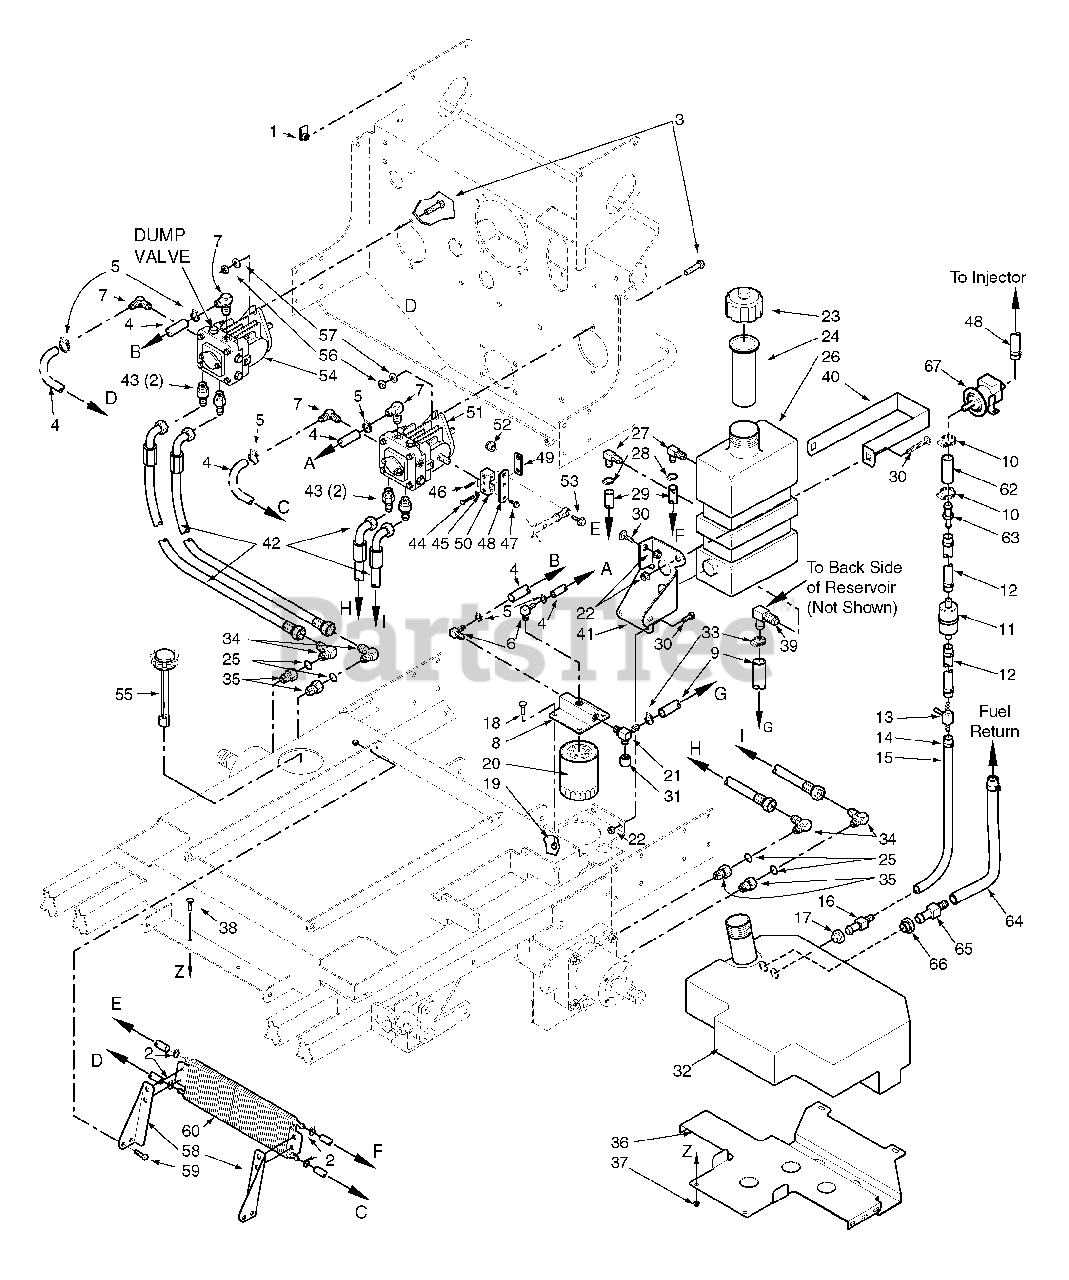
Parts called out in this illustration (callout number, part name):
1	U-Nut 1/4-20
2	Hose Clamp, 0.69 dia.
3	Bolt, Hex Head 1/4-20 x 2.0"
4	Hose, 3/8" ID Pushlock
5	Clamp, Hose 1/2"
6	Elbow, 90 Degree - 1/4 NPT x 3/8 Hose
7	Elbow, 90 Degree - 9/16 O-ring x 3/8 Hose
8	Oil Filter Base
9	Hose Assembly, 1/2" ID (Tank to Filter Base)
10	Clamp, .87 max Dia.
11	Fuel Filter, Kawasaki
12	Fuel Hose, 5/16" ID.
13	Valve, Shutoff Kawasaki
14	Clamp, Fuel Hose
15	Fuel Hose, 5/16" ID.
16	Hose Fitting
17	Bushing
18	Bolt, Hex Head 5/16-18 x 1.0" Zinc
19	Nut, Serrated Flange 5/16-18
20	Oil Filter
21	Tee, 3/4 O-ring x JIC x 1/2" Hose
22	Nut, Hex Elastic Stop 1/4-20
23	Cap, Hydraulic Tank
24	Insert, Filler Neck
25	O-Ring
26	Oil Reservoir Assembly
27	Elbow, 90 Degree .38 Hose
28	Hose Clamp, 0.69 dia.
29	Hose, 3/8" ID, Pushlock
30	Screw, Phillips Head, 1/4-20
32	Fuel Tank Assembly
33	Clamp, Hose
34	Elbow, 90 Degree, 7/8-14 THD
35	Bushing, 7/8-14 JIC x 3/4-16 O-Ring
36	Support Bracket, Fuel Tank
37	Nut, 5/16-18 Serrated Flange
38	Bolt, Carraige 1/4-20 x 3/4"
39	Elbow, 90 Degree
40	Strap, Hydraulic Tank
41	Support Bracket, Hydraulic Tank
42	Hose Assembly, Pump
43	Union, 3/4-16 JIC x 3/4-16 O-ring
44	Bolt, Hex Head, 1/4-20 x 1-14"
45	Lockwasher, 1/4" Spring
46	Roll Pin, Spring 3/16 x 3/4"
47	Bolt, Hex Serrated Flange, 1/4-20 x 3/4"
48	Fuel Hose, 5/16" ID.
49	Clamp Plate, Pump Control
50	Block, Pump Control
51	Pump, Left Hand, BDP-16A
52	Nut, Hex, Elastic Stop 3/8-16
53	Bolt, Hex Head, 3/8-16 x 1-1/4
54	Pump, Right Hand, BDP 16A
55	Cap, Fuel Tank W/Gauge
56	Nut, Hex Elastic Stop 3/8-16
57	Flatwasher, 3/8" (.391 x .938 x .105) Grade 8
58	Mounting Bracket - LH, Oil Cooler
59	Bolt, Hex Head 5/16-18 x 3/4"
60	Cooler, Oil
61	Clamp, .69 Dia.
62	Hose, Fuel Line
64	Hose, 1/4" Fuel Line
65	Fitting, Hose
66	Bushing
68	Fuel Hose, 5/16" ID.
